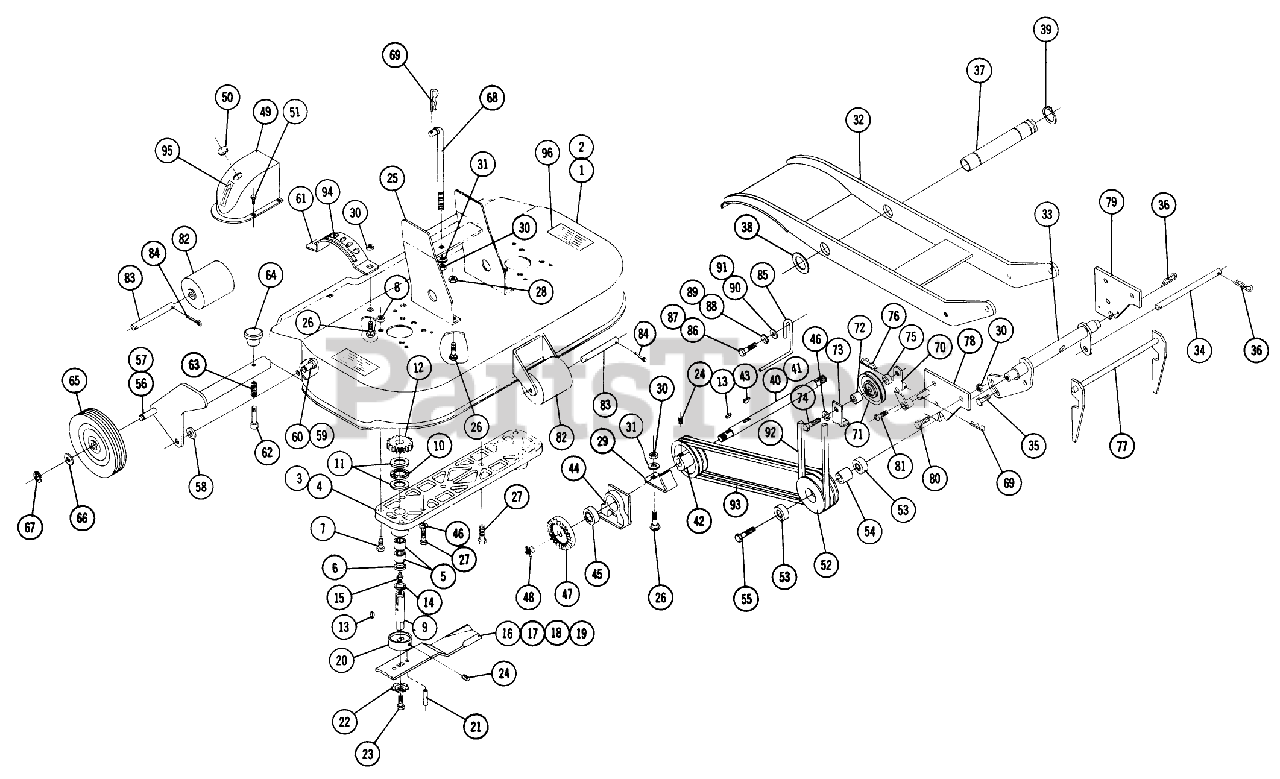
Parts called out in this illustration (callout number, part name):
1	Ass-y. Deck
2	Ass-y Deck
3	Housing
4	Housing
5	NEEDLE BEARING
6	Seal
7	Bolt 5/16-18 x 1
8	Nut-Nylok
9	SPINDLE SHAFT
10	Bearing Thrust
11	Washer-thrust
12	SPUR GEAR
13	WOODRUFF KEY
14	RING-SNAP, EXTERNAL
15	Zerk
16	Blade R.H. 16"
17	Blade L.H. 16"
18	Blade R.H. 18"
19	Blade L.H. 18"
20	SPINDLE CUP
21	SPIROL ROLL PIN
22	WASHER
23	Bolt 3/8-16 x 7/8
24	Set Screw
25	Ass-y Bracket-Hanger
26	Bolt-3/8-16 x 3/4
27	Bolt 3/8-16 x 1
29	Guard
30	3/8-16 E.S.
31	Washer
32	Ass-y-Drag Link
33	ASSY HITCH SHAFT R
34	Pin-Hitch
35	Bolt Whizlock 3/8-16 x 5/8
36	Hairpin
37	PIVOT TUBE
38	Washer
39	SNAP RING
40	SHAFT CROSS
41	SHAFT
42	PULLEY
43	Key
44	Housing
45	Ball
46	Lockwasher
47	Gear
48	Nut Hex 5/8-18 Thin
49	COVER GEAR
50	PLUG BUTTON
51	SCREW
52	PULLEY
53	BALL BEARING
54	SPACER-BEARING
55	SPECIAL BOLT
56	Ass-y-Support-Wheel
57	Ass-y Support-Wheel
58	WASHER
59	Bolt-Special
60	SPECIAL BOLT
61	QUADRANT R
62	PLUNGER
63	Spring
64	KNOB
65	WHEEL ASSY
66	SHIM-WASHER
67	E Ring
68	LIFT ROD R
69	Hairpin
70	Ass-y Idler Arm
71	Pulley
72	SPACER
73	BRACKET GUARD
74	Bolt, 3/8-16 x 1/2
75	BUSHING
76	Hairpin
77	Ass-y Latch & Shaft
78	Ass-y Plate Pin R.H.
79	PLATE-MTG BRKT LH R (NS)
80	Bolt 3/8-16 x 1
81	Bolt 3/8-16 x 1 RD.HD.
82	Roller
83	Shaft
84	Cotter Pin
85	RETAINER BELT
86	Bolt Round Head 5/16-24 x 3/4
87	Bolt 3/8-16 x 3/4
88	Lockwasher
89	Lockwasher
90	Washer
91	Washer
92	V BELT
93	V-BELTS - MATCHED PR
94	Decal-Height Control
95	Decal
96	Decal
